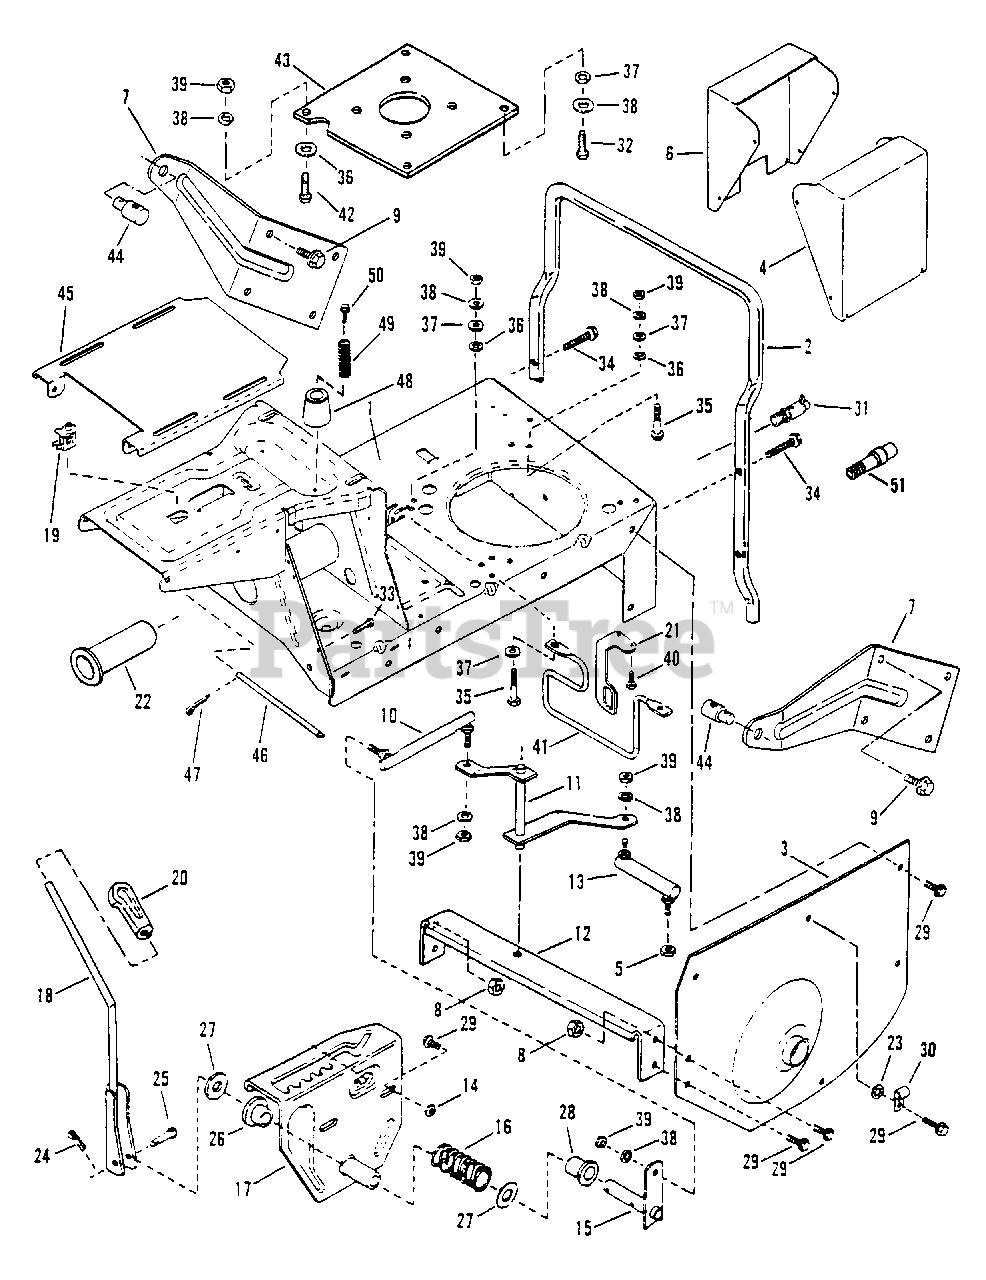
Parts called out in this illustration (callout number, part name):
1	CASE, Main
2	BUMPER, Rear
3	FENDER, Left Hand
4	COVER, Battery
5	NUT, 5/16-24 Hex Flange Lock
6	COVER, Switch
7	WING, Rear
8	NUT, 5/16-18 Hex Flange Lock
9	SCREW, 5/16-18 x 3/4 Self-Tapping
10	LINK, Shift (Long)
11	ARM, Shift
12	BRACE, Cross
13	LINK, Shift (Short)
14	NUT, 5/16-18 Hex
15	ARM, Shift Handle
16	SPRING, Shift Handle
17	DETENT, Shift
18	HANDLE, Shift
19	SWITCH, Seat
20	KNOB, Shift Handle
21	BRACKET, Switch
22	BUSHING, Pilot
23	WASHER, 5/16 Internal Tooth Lock
24	PIN, 3/32 x 3/4" Cotter
25	PIN, 1/4 x 1-3/4" Tapered Clevis
26	BUSHING, Nylon
27	WASHER, Thrust
28	BUSHING, Nylon
29	SCREW, 5/16-18 x 5/8" Self-Tapping
30	CLIP, Wire
31	DRAIN, Oil (1/4 Turn)
32	SCREW
33	FASTENER, 1/4 x 3/4 Ratchet
34	SCREW, 5/16-18 x 1 1/2" Self-Tapping
35	SCREW, 5/16-24 x 1 3/4" Hex Head Cap
36	RETAINER, 5/16 Bolt
37	WASHER, 5/16" Flat
38	WASHER, 5/16" Split Lock
39	NUT, 5/16-24 Hex
40	SCREW, Self Tap, #10 x 1/4"
41	GUIDE, Belt
42	SCREW, 5/16-24 x 1" Hex Head Cap
43	PLATE, Engine
44	SWIVEL
45	PLATE, Seat
46	PIN, Hinge
47	PIN, 1/16 x 3/4 Cotter
48	CUSHION
49	SPRING, Seat O.P.C.
50	SCREW, Self Tapping 1/4-20 x 1/2"
51	DRAIN, Oil
